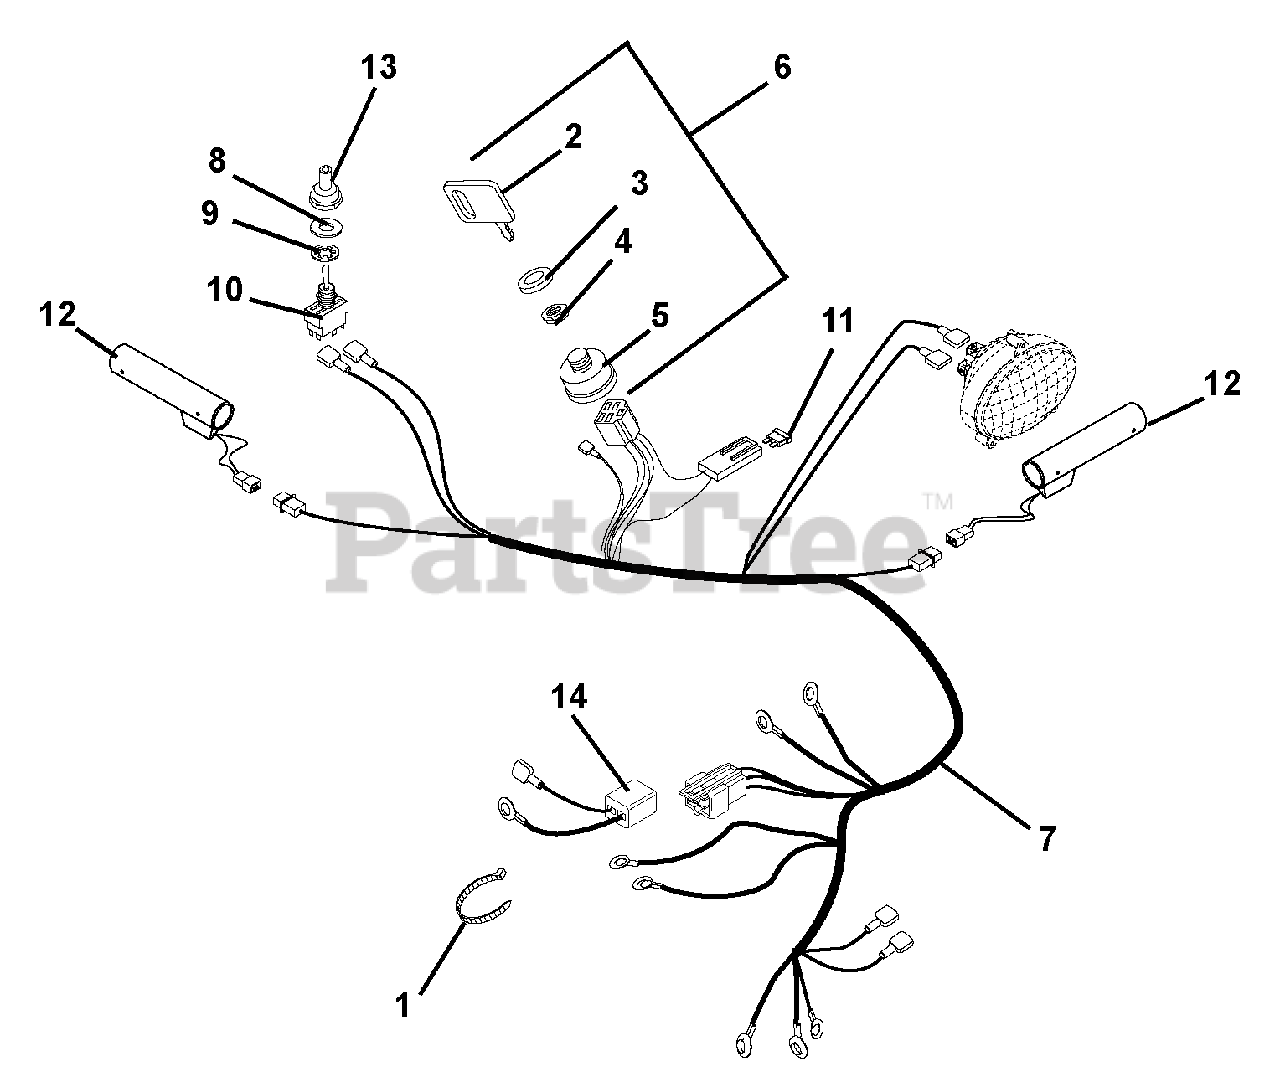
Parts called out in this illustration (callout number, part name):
1	CABLE TIE LG 5-1/2
2	KEY -W/CAP
3	CAP - IGNITION SWITCH
4	NUT-PANEL .625-32 GRECO
5	IGNITION SWITCH ASSEMBLY
6	SWITCH ASSEMBLY
7	HARNESS, WIRE-LIGHT HANDWARMER
7	HARNESS, WIRE-LT, HW, 12V
8	WSHR-FL-STL .505X.875X.024 PL
9	WSHR-LK-INT .563X.040 YWZC
10	SWITCH, ON/OFF
11	FUSE, 15 AMP.
12	WARMER, HAND W/TERMINAL
13	BOOT, SWITCH
14	HARNESS ADAPTER, BRIGGS SPLIT
